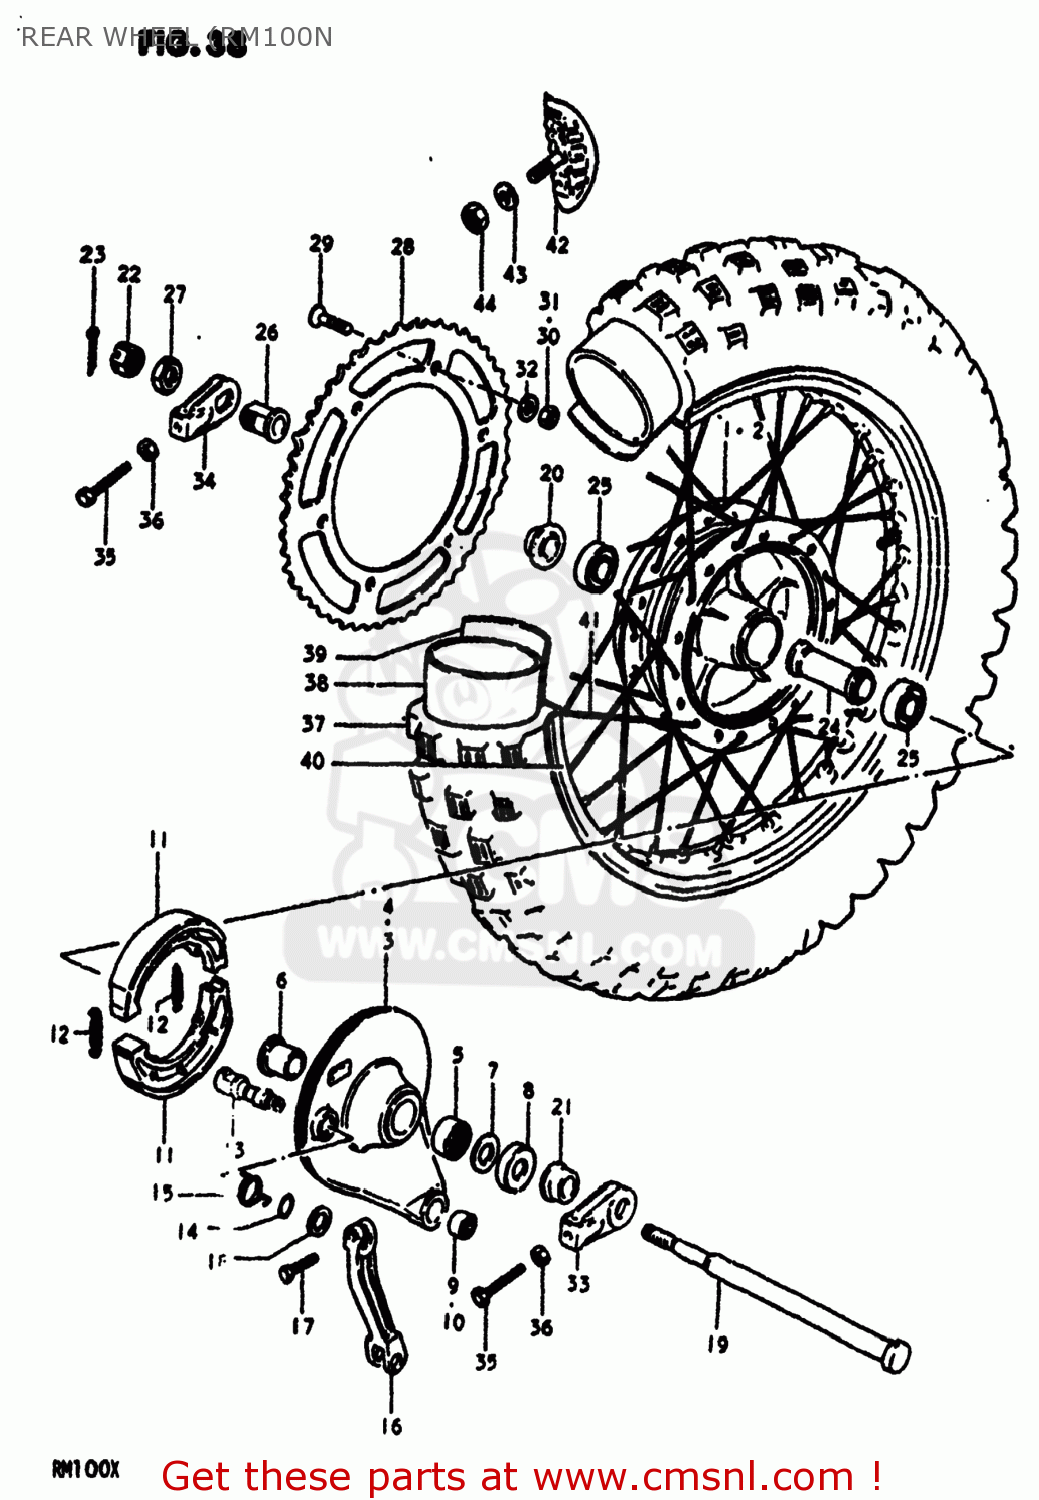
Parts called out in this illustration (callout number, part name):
1	HUB,REAR
2	HUB,REAR
3	PANEL,REAR HUB
4	PANEL SET,REAR HUB
5	BEARING(22X29X25)
6	SPACER,REAR HUB PANEL
7	WASHER
8	COVER, PANEL DUST SEAL
9	BUSH
10	SPHERICAL BEARING,TORQUE
11	SHOE,BRAKE
12	SPRING(L:34)
13	CAM,FR BRAKE
14	O RING(D:2.5,ID:11.4)
15	SPRING
16	LEVER,RR BRAKE CAM
17	BOLT
18	WASHER(12.5X20X1)
19	AXLE,REAR
20	SPACER,RR AXLE,L
21	SPACER (15.2X26X34)
22	NUT 12MM
23	COTTER PIN
24	SPACER,REAR HUB BEARING
25	BEARING
26	SPACER,CHAIN ADJUSTER,L
27	NUT
28	SPROCKET,REAR
29	SCREW(8X33.5)
30	NUT
31	NUT
32	WASHER
33	ADJUSTER,CHAIN,R
34	ADJUSTER,CHAIN,L
35	BOLT(8X40)
36	NUT
37	TIRE
38	TUBE ASSEMBLY,WHEEL,INNER
39	PROTECTOR,INNER TUBE
40	RIM,REAR WHEEL
41	SPOKE SET,REAR
42	STOPPER,BEAD
43	WASHER
44	NUT
